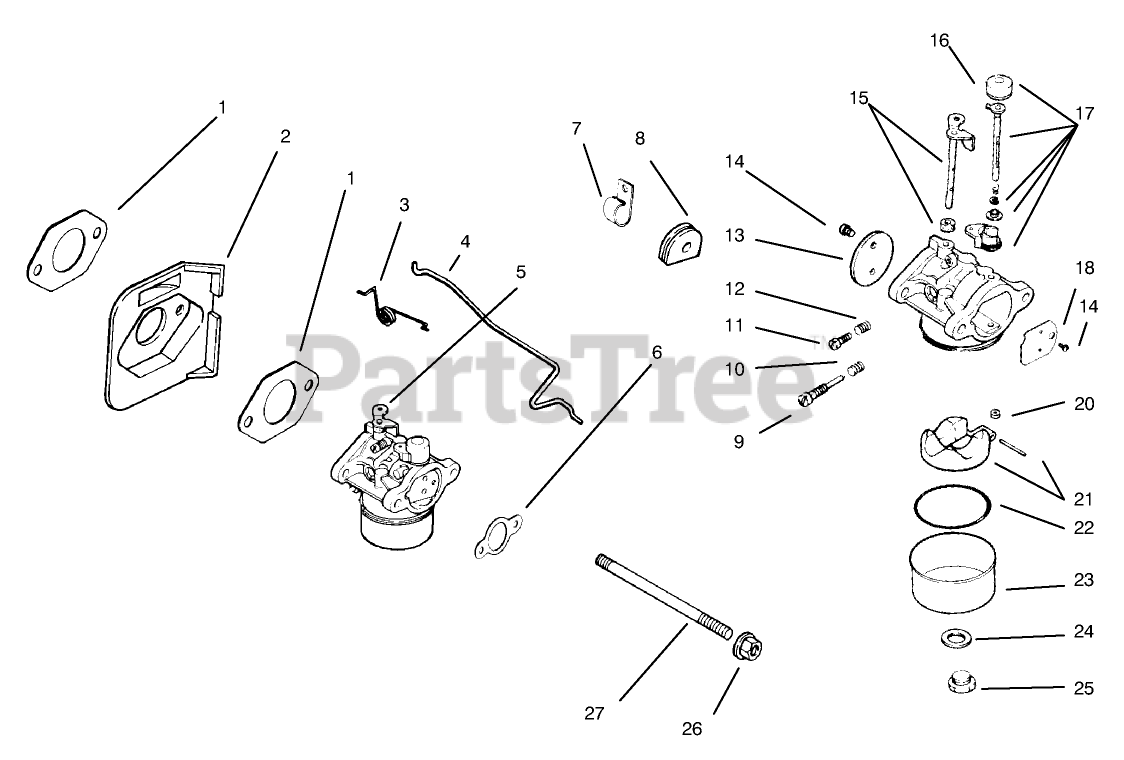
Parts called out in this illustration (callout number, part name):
1	Gasket-Carburetor
2	Deflector-Heat
3	Spring Choke
4	Linkage Choke
5	Carburetor ASM Incl 9-25
6	Gasket-Air Cleaner
7	Clamp
8	Grommet
9	Needle-Idle
10	Spring-Idle
11	Screw-Idle
12	Spring-Idle
13	Plate-Choke
14	Screw
15	Shaft-w/Lever & Seal
16	Cap-Choke Lever
17	Kit-Choke Repair
18	Plate-Choke
20	Jet-Main
21	Kit-Float
22	Gasket-Bowl
23	Bowl-Fuel
24	Gasket-Bowl
25	Screw-Bowl
26	Nut
27	Stud
